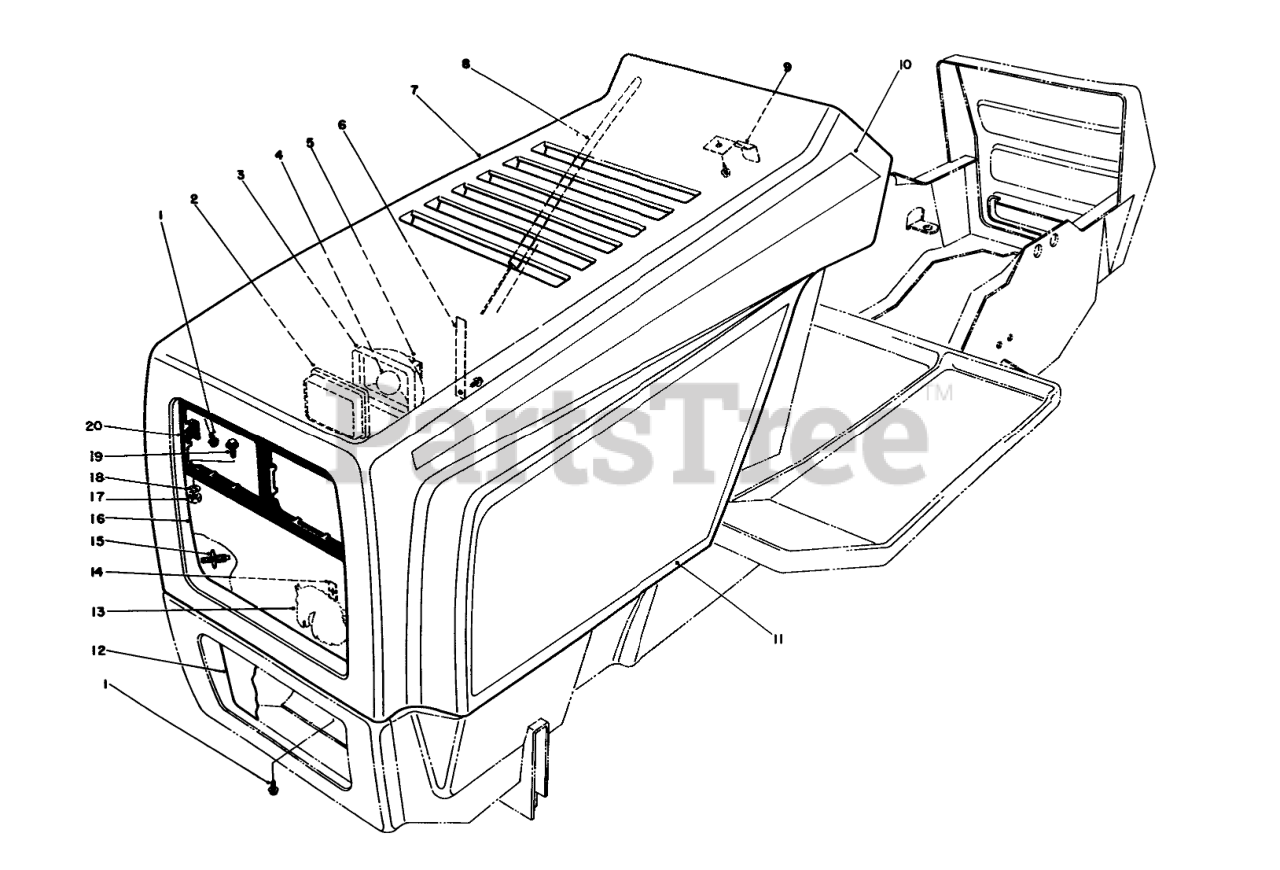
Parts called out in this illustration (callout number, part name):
1	SCREW-HWHTF
2	Lens
3	Reflector
4	Bulb
5	Socket
6	HEADLIGHT STRAP
7	Hood (Incl. Ref. #15)
8	RUBBER EXT SEAL
9	SPRING LATCH
10	DECAL - RH HOOD TRIM
11	LH HOOD DECAL
12	LOWER GRILLE
13	EMBLEM-GRILLE WHEELHORSE
15	HINGE BRKT STUD
16	HEADLIGHT GRILLE
17	NUT-LOCK, SIDE
18	WASHER-FLAT
19	SCREW-SHWH
20	HEADLIGHT PANEL
